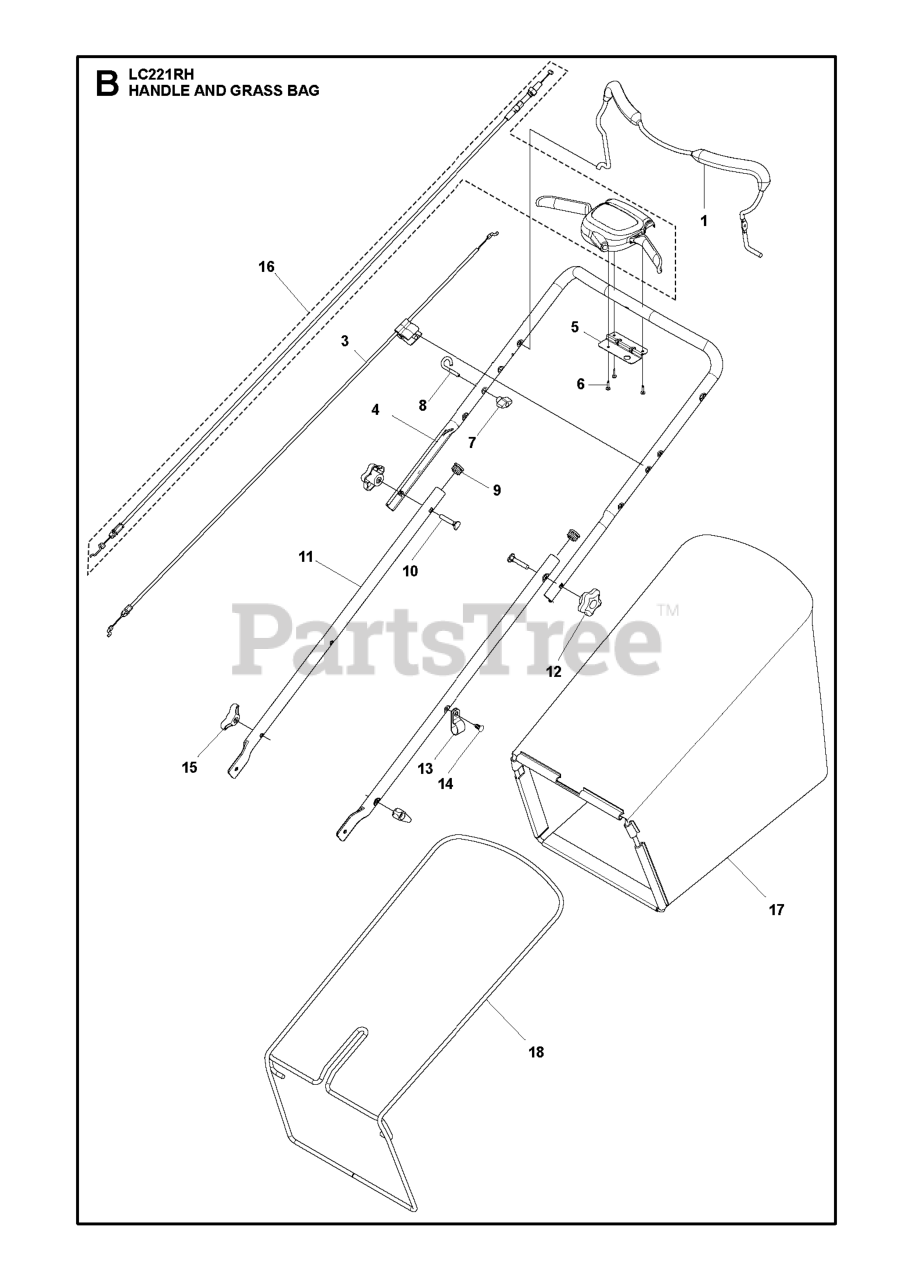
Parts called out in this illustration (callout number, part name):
1	BAIL.OM.ERGO.BENT.MZR.ORAN.668
2	CONTROL.RWD.AW2.BS.21EFF.H01
3	CABLE.MZR.50.SNAP-IN
4	HANDLE.UPPER.3.POS.BS.AW2.GREY
5	BRACKET DUAL TRIGGER CONTROL
6	SCREW, PHILLIPS HEAD 10 X 5/8
7	T-KNOB.NEW ROPE GUIDE
8	GUIDE.ROPE.BLK.ZINC.CHROM
9	PLUG.PLASTIC.7/8".14-20.GAUGE
10	BOLT.CONCAVE.HEAD.RETAINING
11	HANDLE.LOW.2PC.2POS.21EFF.498
12	KNOB.HANDLE.PLASTIC.STAR.BLACK
13	CLIP.CABLE.BLK
14	FASTENER.PUSH.O.250X0.783
15	KNOB, DEFLECTOR
16	CONTROL.RWD.AW2.BS.21EFF.H01
17	GBAG.C361029ER.HUSQ.GRY.21EFF
18	FRAME.GBAG.AWD.21.BLACK
